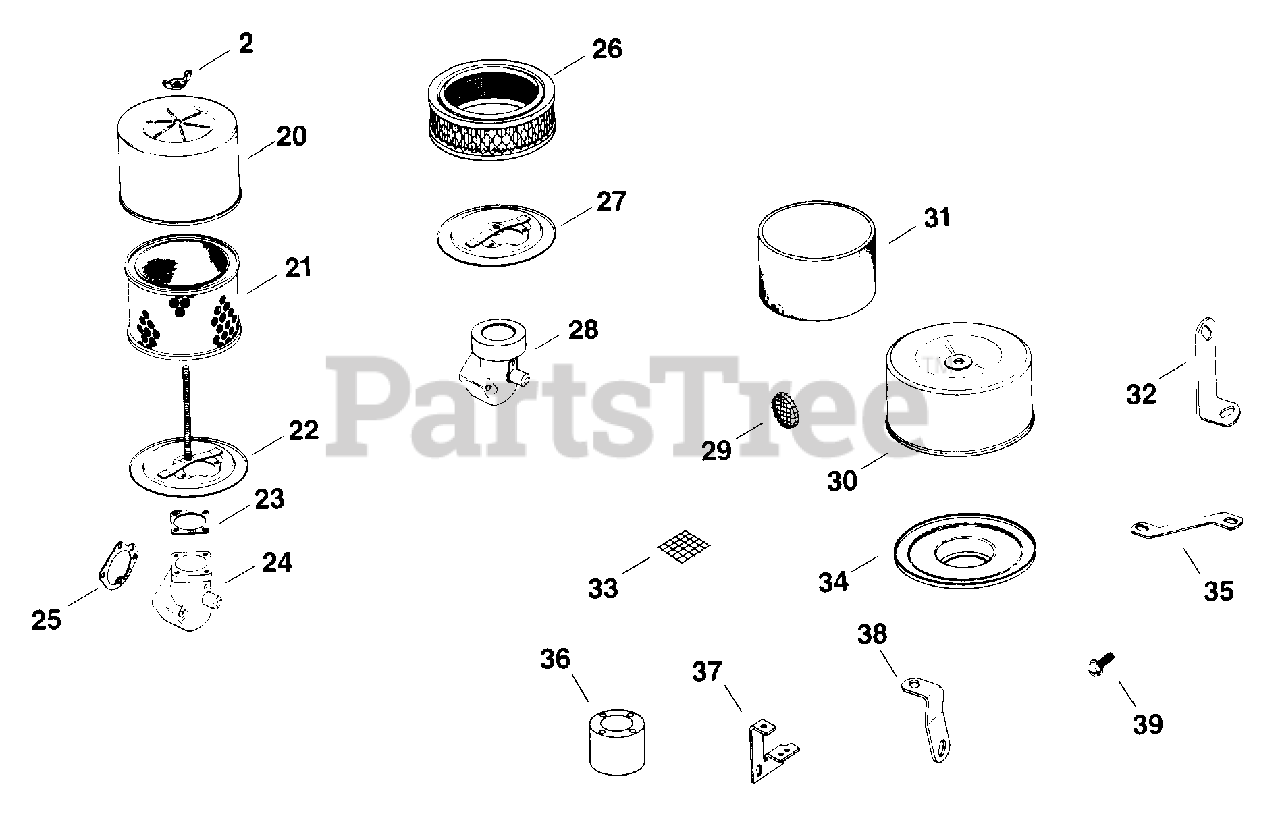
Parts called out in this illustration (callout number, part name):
2	NUT, WING 1/4-20 USE 25 100 15-S
20	COVER - (#DSC)
22	BASE, AIR CLEANER - (#DSC)
23	GASKET, AIR CLEANER
24	GASKET, AIR CLEANER ELBOW
25	ELBOW - USE 48 754 01
35	BRACE, AIR CLEANER ELBOW - (#DSC)
